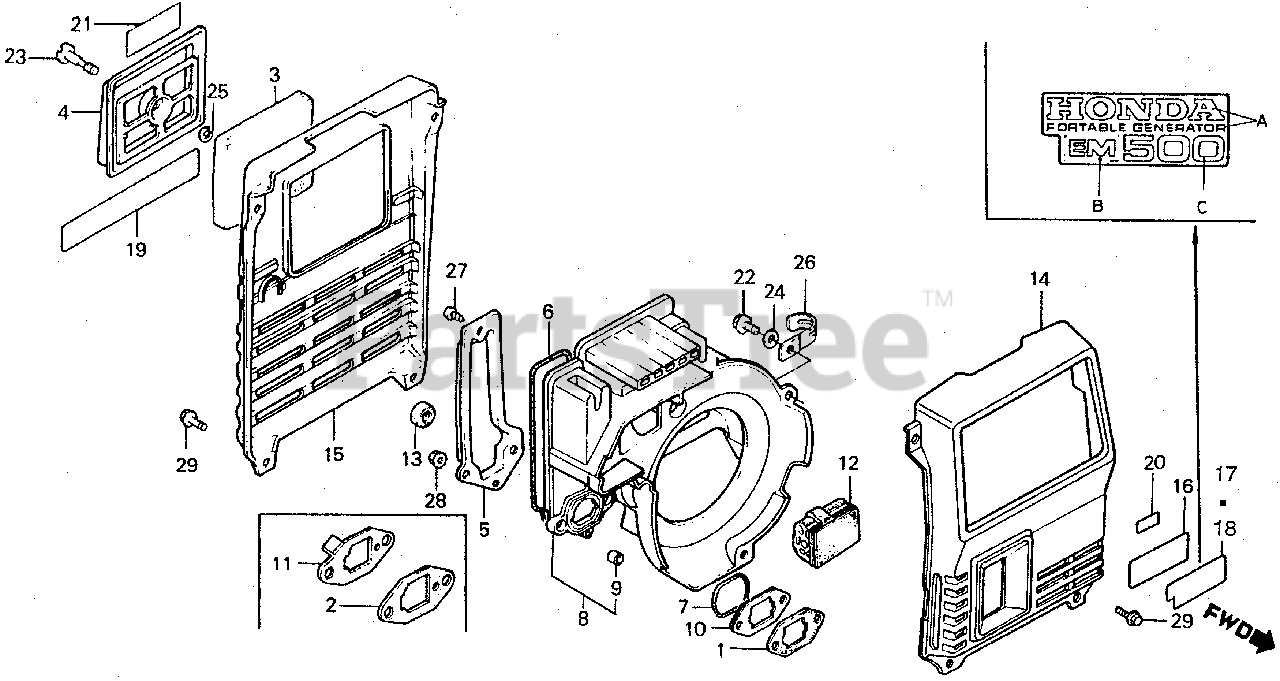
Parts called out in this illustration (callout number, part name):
1	GASKET, AIR CLEANER
3	ELEMENT, AIR CLEANER
4	COVER, AIR CLEANER (NOT AVAILABLE)
5	COVER, MUFFLER
6	RUBBER, MUFFLER SEAL (NOT AVAILABLE)
7	O-RING, MUFFLER (NOT AVAILABLE)
8	COVER, FAN (NOT AVAILABLE)
9	COLLAR, FAN COVER (NOT AVAILABLE)
10	BRACKET, FAN COVER (NOT AVAILABLE)
12	GROMMET, FAN COVER
13	RUBBER, STOPPER (NOT AVAILABLE)
14	COVER, FR. *NH44MS* (SPECIAL SILVER METALLIC)
15	COVER, RR. *NH44MS* (SPECIAL SILVER METALLIC)
16	EMBLEM
17	EMBLEM
19	PLATE, CAUTION
20	MARK C, CAUTION (NOT AVAILABLE)
21	MARK, AIR CLEANER
22	BOLT, FLANGE (5X10)
23	BOLT, AIR CLEANER COVER (NOT AVAILABLE)
24	WASHER, STOPPER (5MM)
25	E-RING (4MM)
26	CLIP A, WIRE
27	SCREW, TAPPING (4X10)
28	NUT, FLANGE (5MM)
29	BOLT, FLANGE (6X10)
